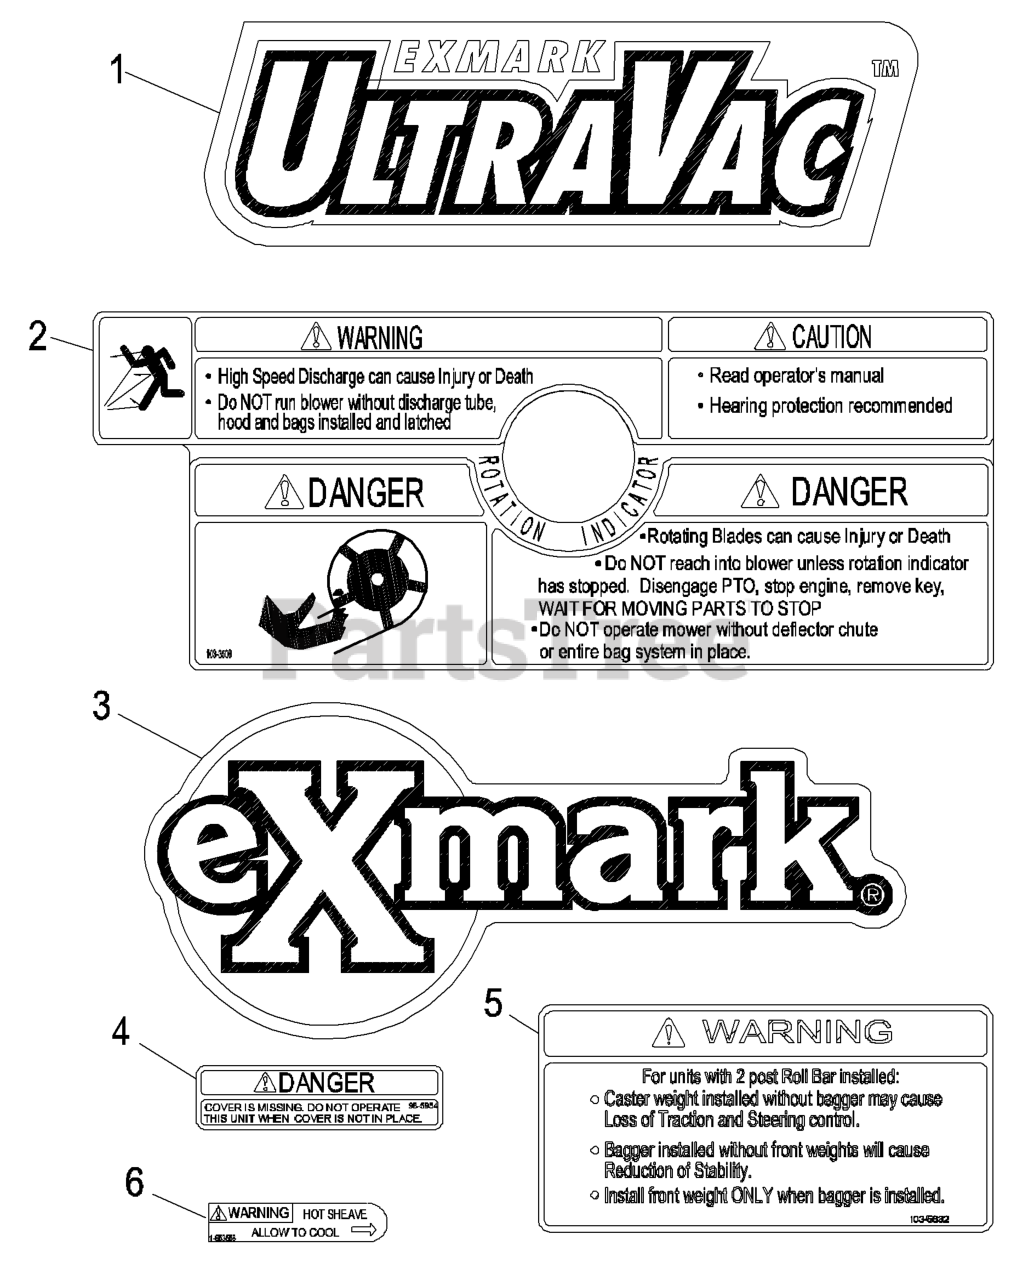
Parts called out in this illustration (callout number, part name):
1	DECAL, ULTRAVAC
2	DECAL-WARNING
3	DECAL, EXMARK LOGO
4	DECAL-COVER, MISSING
6	DECAL-WARNING
